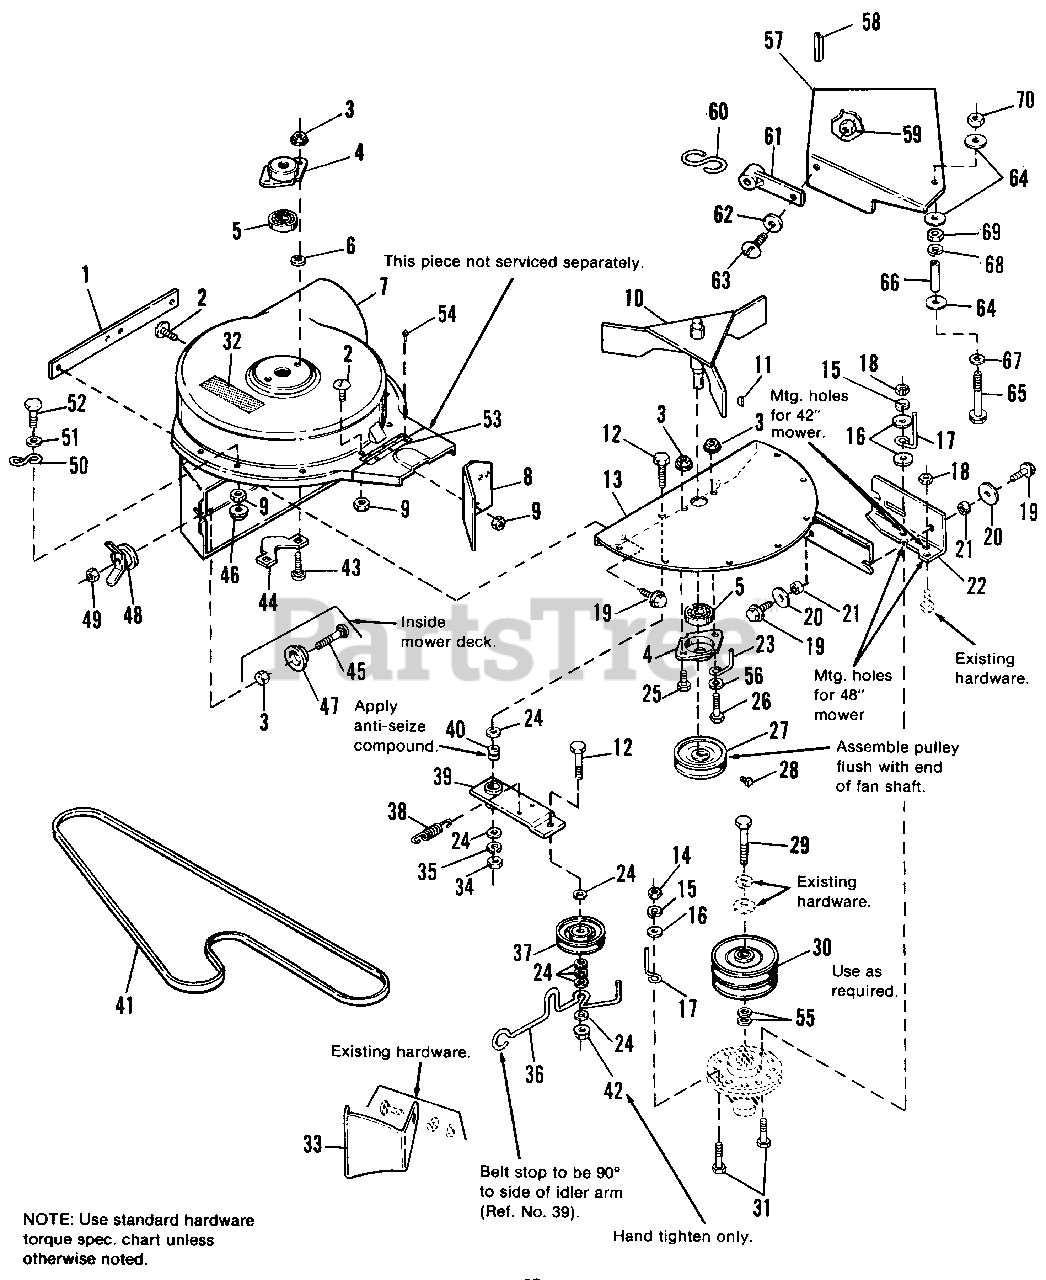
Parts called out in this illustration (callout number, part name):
1	STRAP, Reinforcement, Blower Housing
2	CAPSCREW, Hex Hd., 1/4-20 x 5/8
3	NUT, Flange Lock, 5/16-18
4	BEARING, Retainer
6	PUSHNUT, 5/16
7	FAN HOUSING & HINGE ASSY. (Inc. Ref. Nos. 32, 53 & 54)
8	BAFFLE, Fan Housing
9	NUT, Hex, Nylon Lock, 1/4-20
10	FAN ASSY.
11	KEY, Woodruff #61, 3/16 x 5/8
12	CAPSCREW, Hex, 3/8-16 x 1-3/4
13	PLATE ASSY.
14	NUT, Hex, Full 5/16-18
15	LOCKWASHER, 5/16
16	WASHER, Plain
18	NUT, Hex Jam Lock, 5/16-18
19	SCREW, Taptite, 1/4-20 x 5/8
20	WASHER, 1/4
22	BRACHET, Arbor
23	STOP, Belt
24	WASHER, Plain, 13/32
25	CAPSCREW, Hex, 5/16-18 x 1/2
26	CAPSCREW, Hex, 5/16-18 x 3/4
27	PULLEY, Driven
28	SETSCREW, Sq. Hd., 5/16-18 x 5/8
29	CAPSCREW, Hex, 7/16-14 x 2-1/4
30	PULLEY ASSY.
31	CAPSCREW, Hex, 5/16-18 x 1-1/2
32	DECAL, Danger, Blower
33	BAFFLE, Discharge
34	NUT, Hex, Full, 3/8-16
35	LOCKWASHER, 3/8
37	PULLEY, Idler
38	SPRING, Tension
39	IDLER ARM ASSY.
40	SPACER
41	BELT, Turbo
42	NUT, Hex, Flange Lock, 3/8-16
43	CARRIAGE BOLT, 5/16-18 x 3/4
44	PLATE, Flange, Blower Housing
45	CARRIAGE BOLT, 5/16-18 x 2-1/4
46	NUT, Flange Lock, 1/4-20
48	NUT ASSY., Wing
49	NUT, Hex, Full, Lock, 5/16-18
51	WASHER, Plain, 9/32
52	CAPSCREW, Hex Hd., 1/4-20 x 1-1/4
55	WASHER (As Required)
56	WASHER, 11/32
57	COVER ASSY., Pulley
58	MOLDING
59	NUT, Hex, Full Lock, #10-32
60	"S" HOOK
61	STRAP
62	WASHER, Special
63	SCREW, Truss, #10-32 x 1/2
64	WASHER, Special
65	CAPSCREW, Hex, 5/16-18 x 5-1/2
66	SPACER
67	WASHER, 5/16
68	LOCKWASHER, 5/16
69	NUT, Hex, Full, 5/16-18
70	NUT, Hex, Full, Lock, 5/16-18
